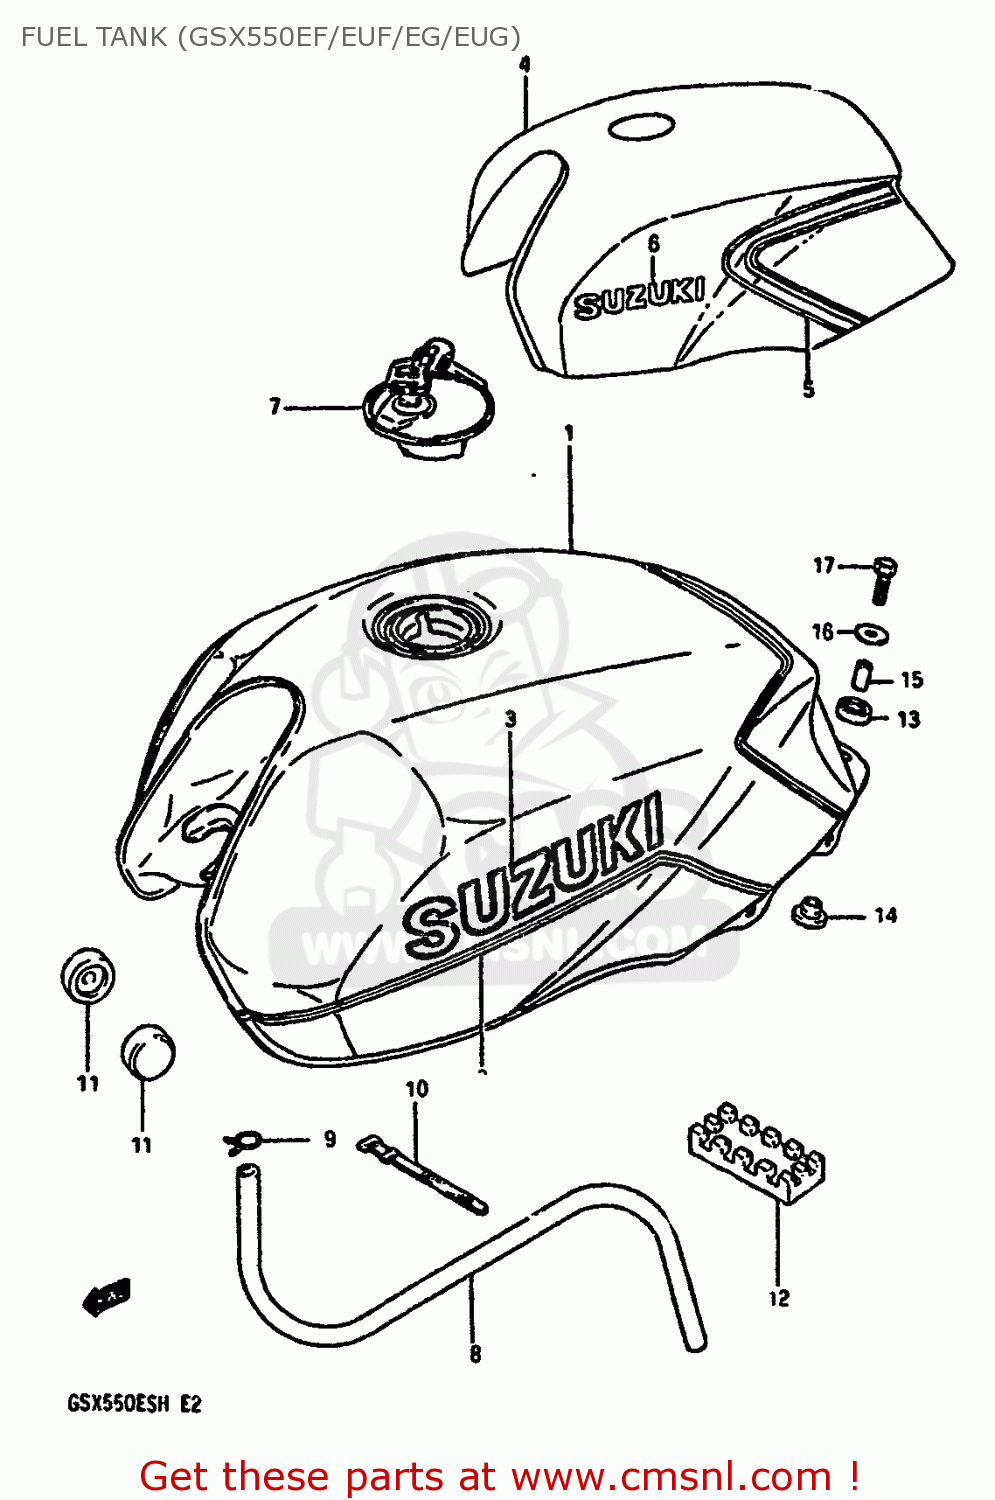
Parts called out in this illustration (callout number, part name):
1	TANK ASSY,FUEL
2	TAPE SET,FUEL TANK
3	EMBLEM
4	TANK ASSY,FUEL
5	TAPE SET,FUEL TANK
6	EMBLEM
7	CAP ASSY,FUEL TANK
8	HOSE,FUEL
9	CLIP
10	CLAMP(L:187)
11	CUSHION
12	CUSHION,FUEL TANK
13	CUSHION
14	CUSHION
15	SPACER (6.4X9X20)
16	WASHER (6.5X24X1.6)
17	BOLT
